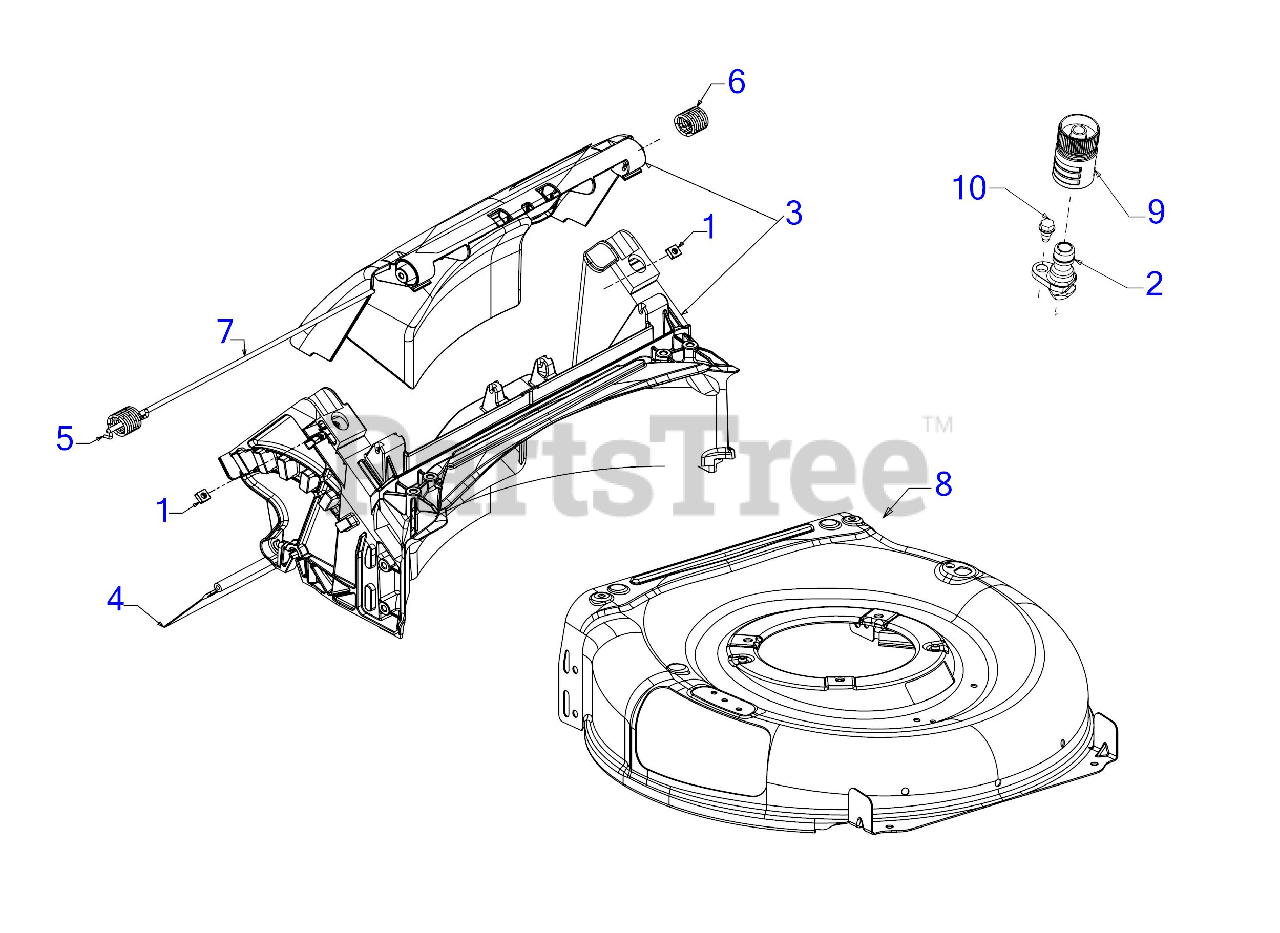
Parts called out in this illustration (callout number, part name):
1	SQUARE NUT 1/4-20
2	DECK WASH NOZZLE
3	REAR BAG DOOR ASSEMBLY
4	TRAILSHIELD
5	TORSION SPRING (RH)
6	TORSION SPRING (LH)
7	REAR DOOR PIVOT ROD
9	WATER NOZZLE
10	SHOULDER SCREW 1/4-20 x .50
